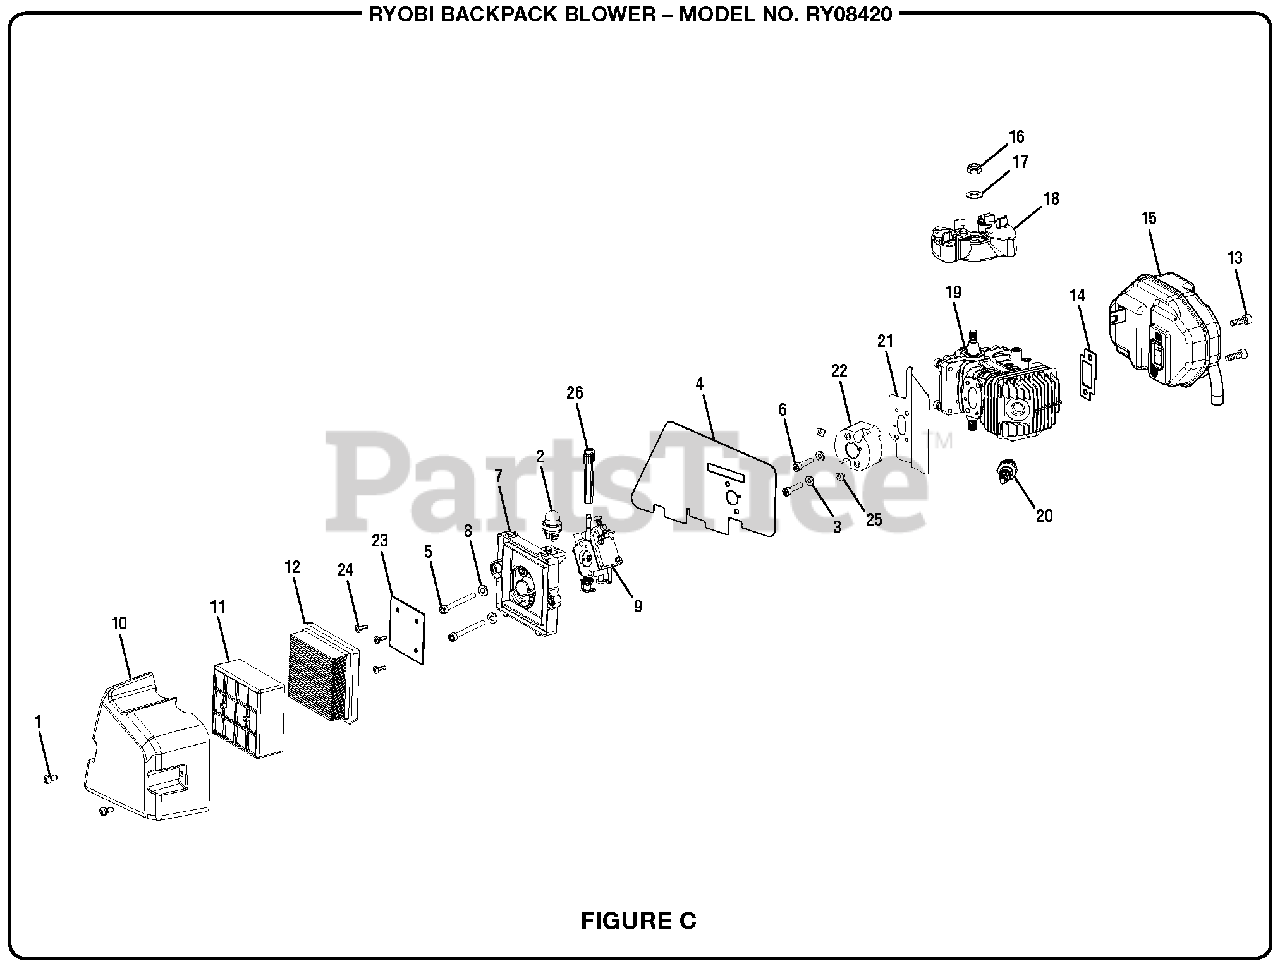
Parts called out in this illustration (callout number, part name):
1	Screw (M5, Special)
2	Primer Assembly
3	Spring Washer (M5)
5	Screw (M5 x 50 mm, Soc. Hd.)
6	Screw (M5 x 0.8 in.)
7	Air Box Base
8	Washer (ID5.8 x OD11.5 x 1.7t)
9	Carburetor
10	Air Box Cover
11	Air Filter Box
12	Air Filter
13	Bolt (1/4-20 x 18 mm)
15	Exhaust Assembly
16	Lock Nut (M8)
17	Washer (ID9 x OD17.7 x 1.1t)
18	Flywheel Assembly
19	Short Block Assembly
20	Spark Plug (RCJ4)
22	Heat Dam
24	Screw (M4 x 12 mm, Pan Hd.)
25	Washer (Heat Dam)
26	Choke Lever
